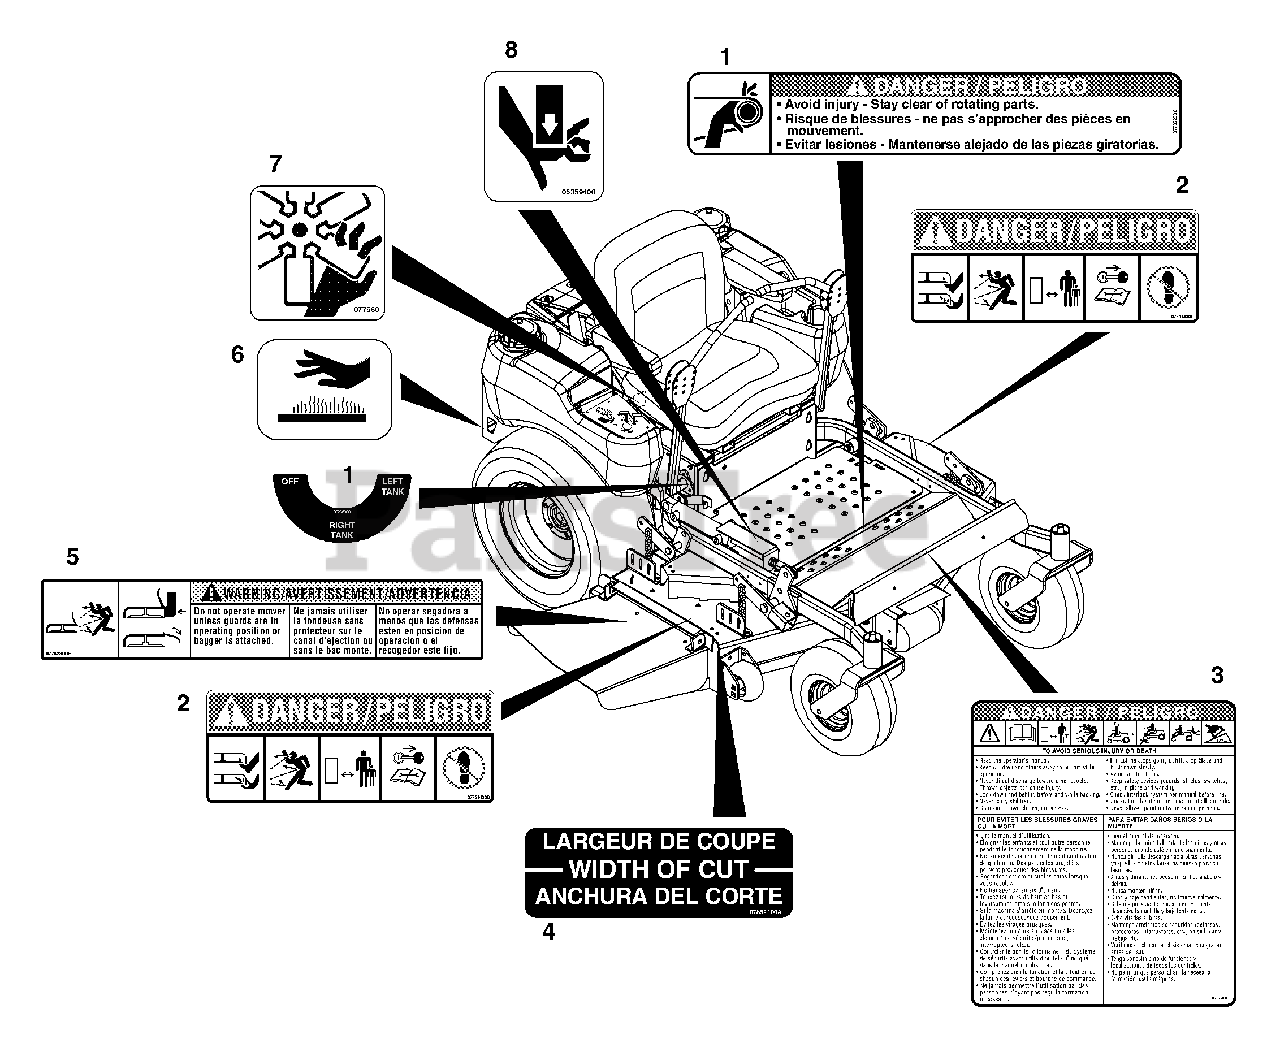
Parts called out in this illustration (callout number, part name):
1	Set, Decal-Common Danger/Fuel
2	Decal, Mower Pan Head Danger
3	Decal, Danger- Bilingual
4	Decal, Width of Cut
5	Decal, Warning
6	Decal, Hot Surface
7	Decal, Danger Fan
8	Decal, Pinch Point
